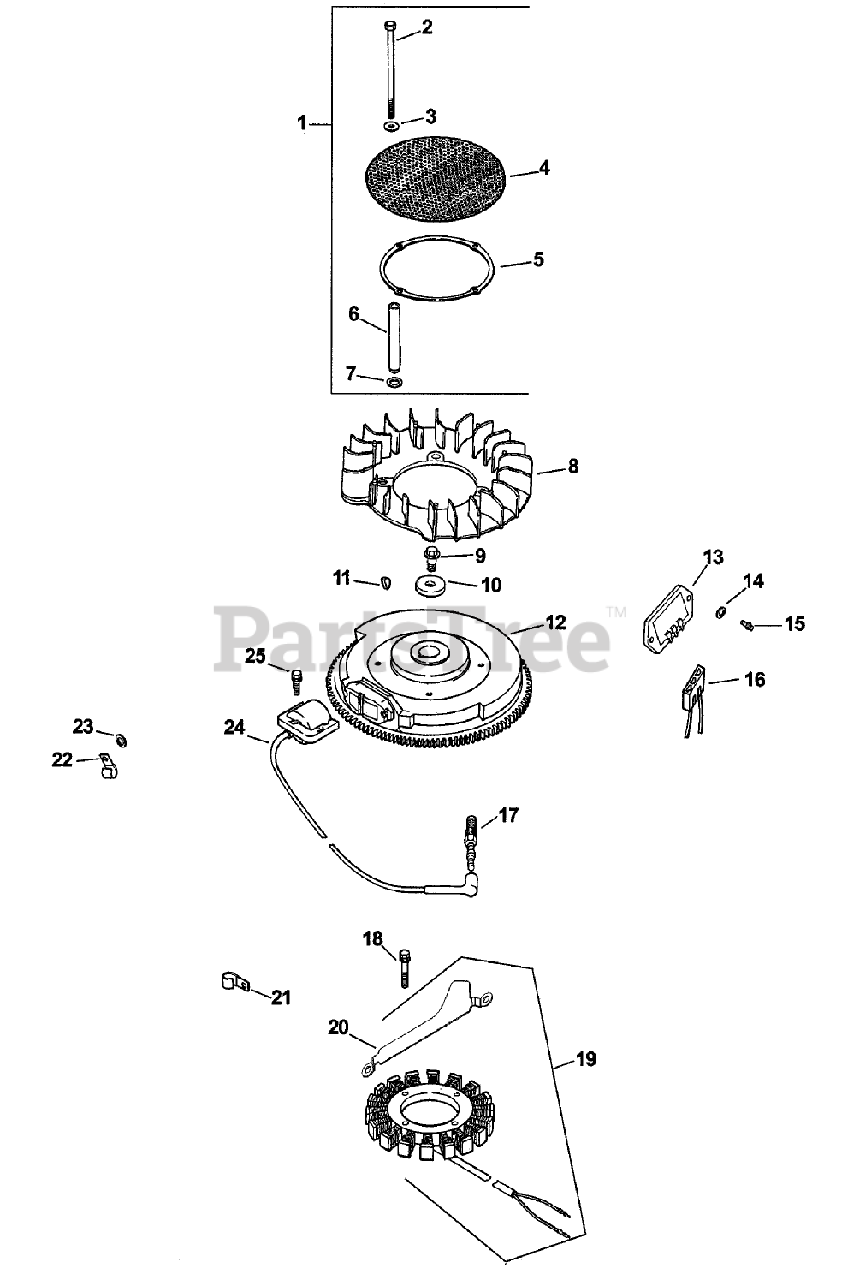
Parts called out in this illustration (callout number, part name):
1	Kit, chopper screen (Includes 2-7)
2	Screw, hex. cap
3	WASHER-FLAT (1/4)
4	Screen-Grass
5	Ring-Support
6	Spacer
7	Washer-Spring (10MM)
8	Fan
9	SCREW-FLANGE (M10X1.5X45)
10	WASHER-FLAT (13/32)
11	KEY (3/16 X 5/8)
12	Flywheel
13	Rectifier-Regulator, 15 amp
14	WASHER-FLAT (.188)
15	SCREW-PHL HD (11-16X.88)
16	Connector (3 contact)
17	Spark Plug
18	Screw
19	Kit, 15 amp stator (Includes Bracket, stator wire 24 126 71)
20	Bracket-Wire, Stator
21	CLIP-CABLE
22	Clip-Cable
23	WASHER-FLAT (1/4)
24	Module-Ignition
25	Screw
